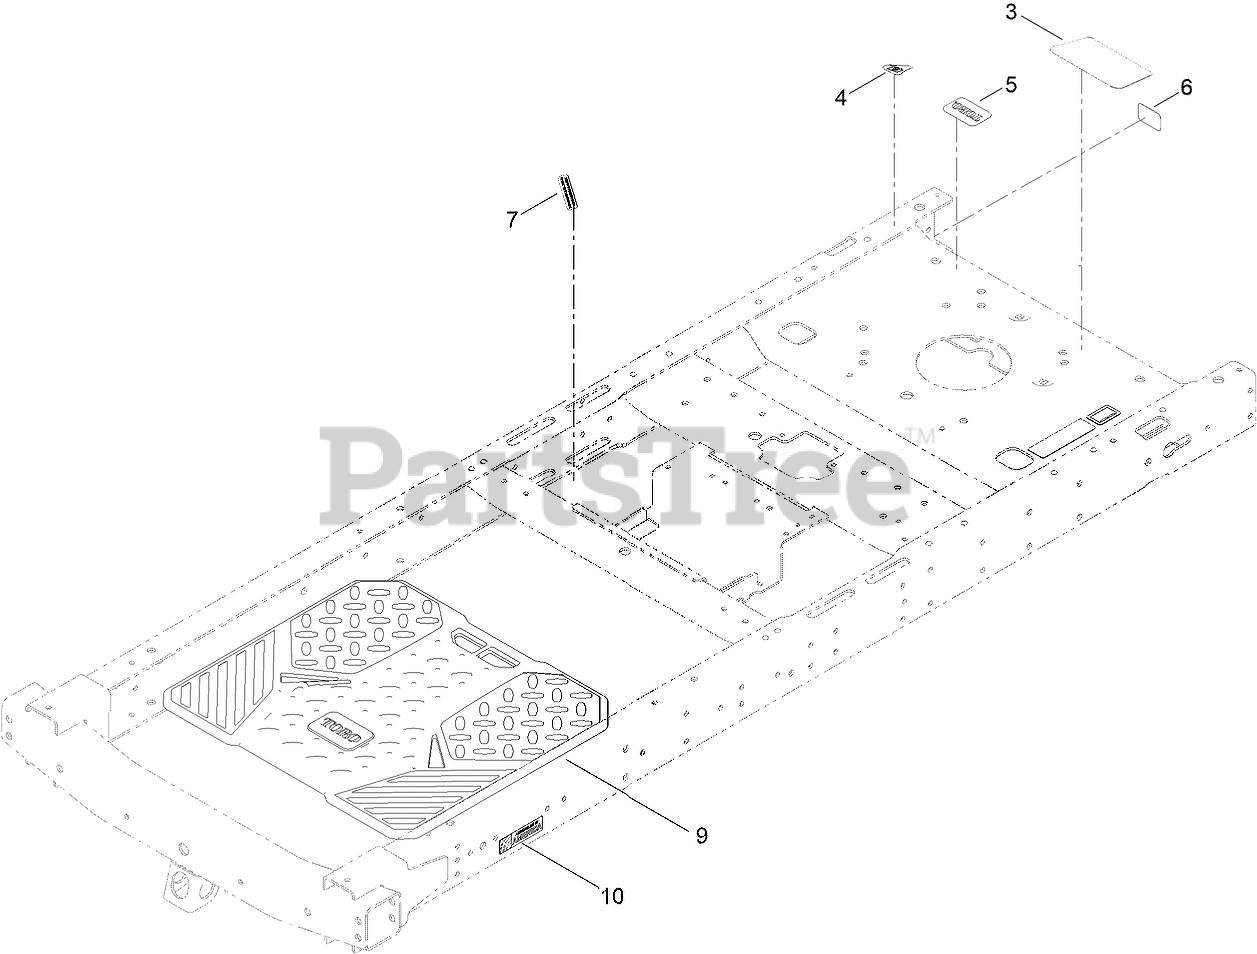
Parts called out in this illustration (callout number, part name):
3	DECAL-ENGINE
4	DECAL-DRAIN, OIL
6	PLACARD-INTAKE
7	DECAL-SHUTDOWN
9	FLOOR MAT
